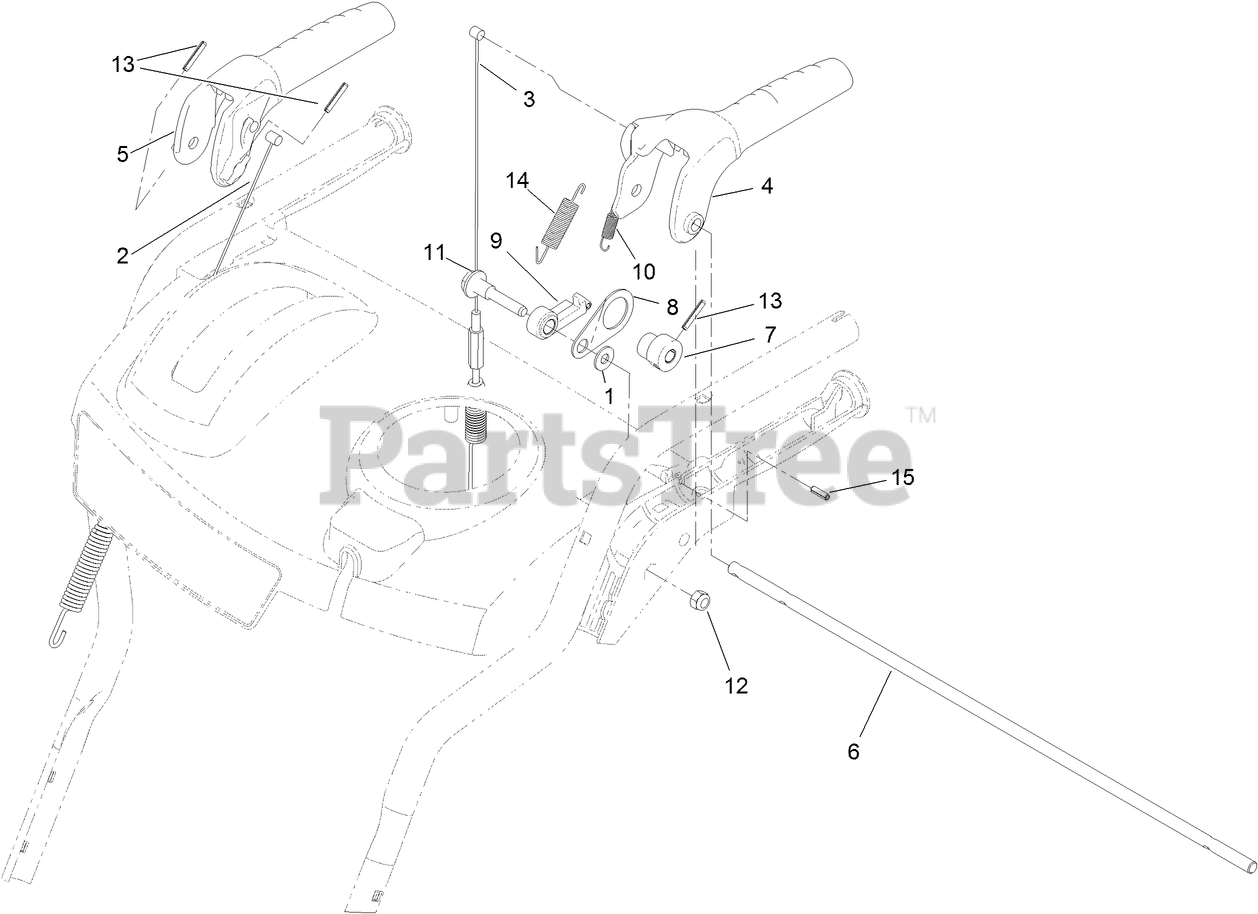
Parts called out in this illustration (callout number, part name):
1	WASHER-FLAT
2	CABLE-AUGER
3	CABLE-TRACTION
4	HANDLE-CONTROL, TRACTION
5	HANDLE-CONTROL, AUGER
6	ROD-LOCKOUT
7	CAM-LOCKOUT
8	LINK-LOCKOUT
9	LATCH-LOCKOUT
10	SPRING-LOCKOUT, HANDLE
11	SCREW-SHOULDER
13	PIN-SPRING
14	SPRING-RETURN, LEVER
15	PIN-ROLL, SLOTTED
